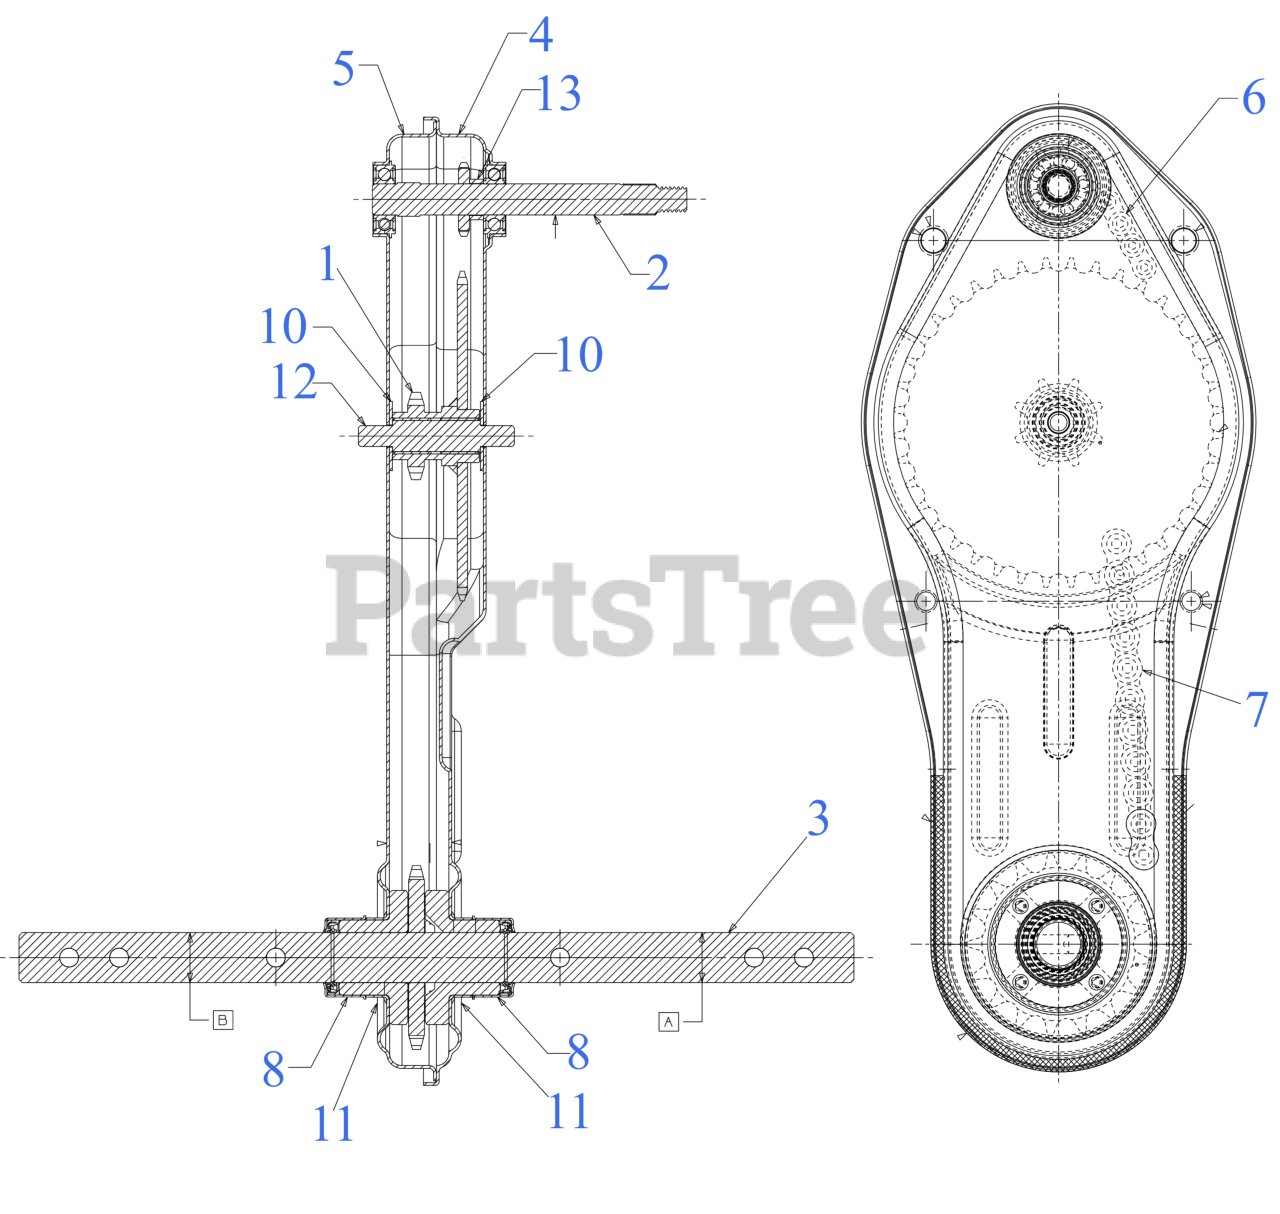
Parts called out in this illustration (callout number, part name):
3	TINE SHAFT ASM
4	CASE ASM:CHAIN:LH
5	CASE ASM:CHAIN:RH
6	#420 CHAIN 1/2 PITCH
7	#50 CHAIN 5/8 PITCH
8	SHAFT SEAL 1" DIA
10	FLAT WASHER
11	BENALENE GREASE 920 8 OZ
12	SHF:JACK
13	SPCR:INPUT SHAFT
